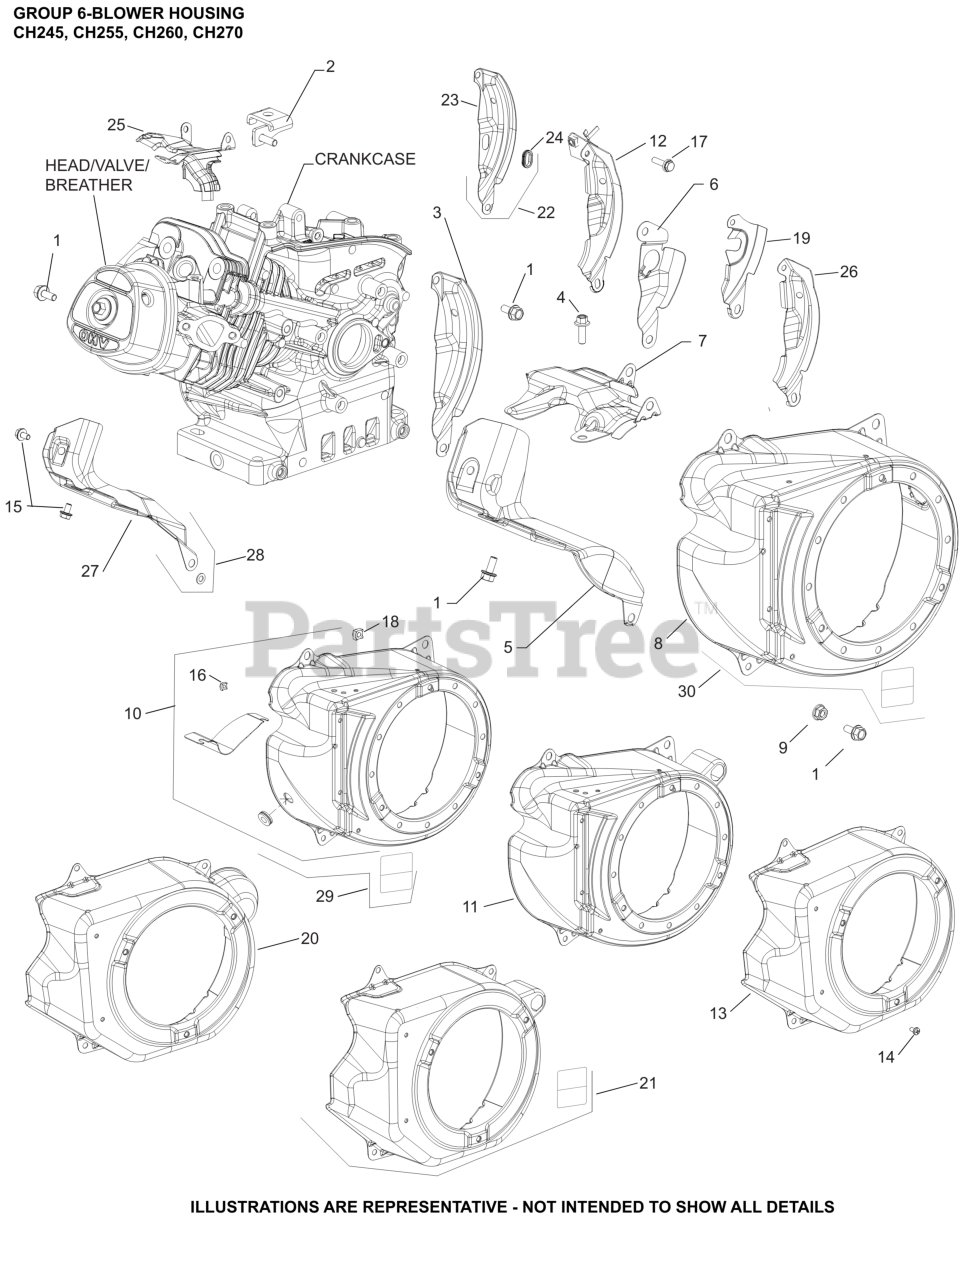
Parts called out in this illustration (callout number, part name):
1	SCREW, HEX FLANGE (M6)-USE 25 086 433-S
9	NUT, HEX FLANGE (M6) - USE 14 100 16-S
12	COVER, HOUSING LOWER BLOWER ASSEM
14	SCREW, COVER TO BLOWER HOUSING
15	SCREW, HEX FLANGE (M6)
17	SCREW, M6 X 22
20	KIT, BLOWER HOUSING
25	FLOW SHIELD
28	KIT, CYLINDER SHIELD
